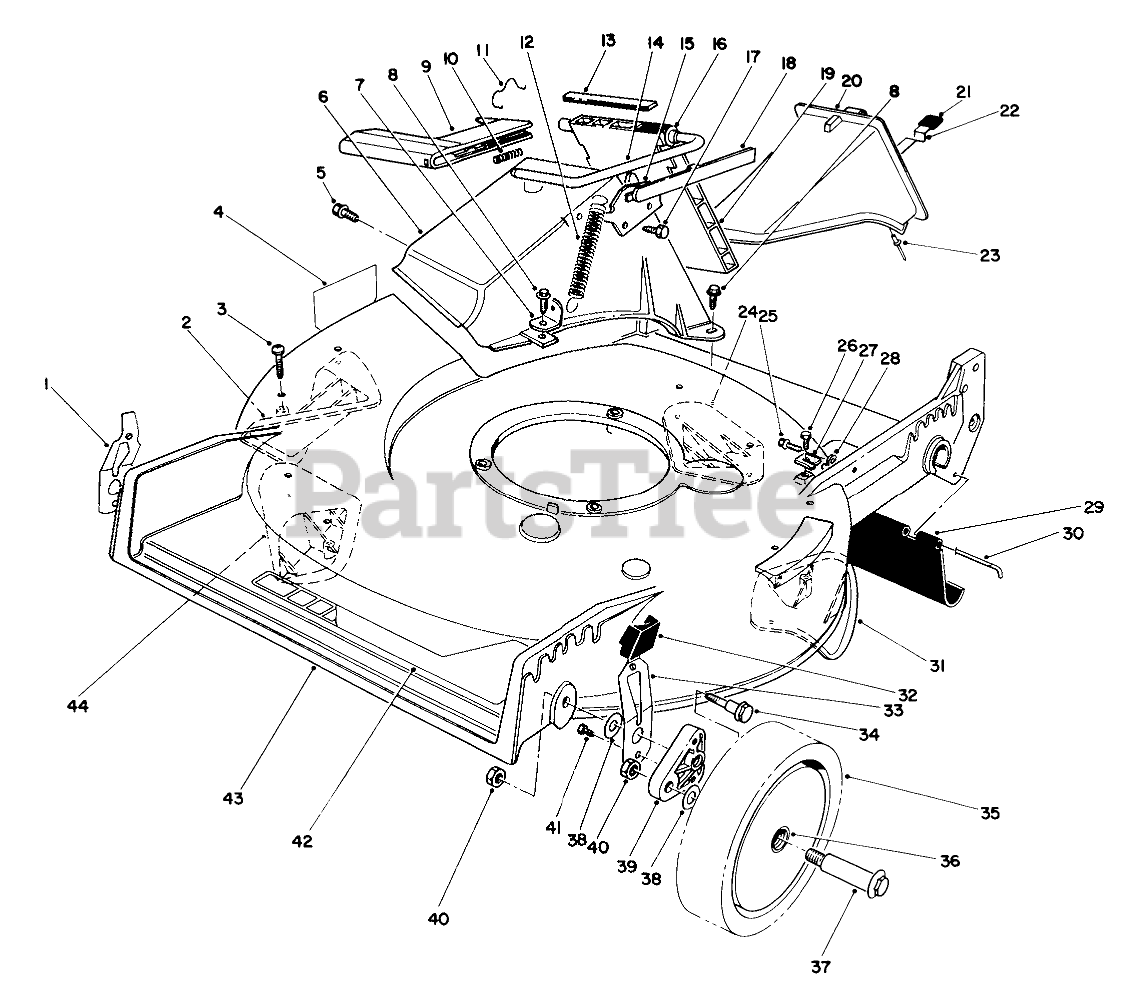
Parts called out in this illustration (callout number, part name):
1	RH SPRING ARM ASSEMBLY
2	KICKER
3	#8 X .625" PHILPS PAN H
4	DECAL-DANGER
5	SCREW AND WASHER ASM
6	Tunnel-Discharge
7	Bracket-Spring
8	SCREW-HWH
9	Handle-Door
10	Spring
11	DOOR RET SPRING
12	SPRING-DOOR
13	Cover-Door
14	Rod-Door
15	DOOR LATCH PLATE
16	BUSHING-NYLON
17	SCREW-PLASTITE
18	Cover-Handle
19	Door-Discharge
20	Plug
21	GRIP-LATCH
22	LATCH-PLUG, DISCHARGE
23	RIVET-HEAD, FLAT
24	PLATE-KICKER
25	SCREW
26	SCREW-HWHTF
27	CLAMP-CABLE
28	CLAMP-CABLE
29	SHIELD-TRAILING
30	ROD-SHIELD
31	KICKER
32	KNOB-ARM
33	LH SPRING ARM ASSEMBLY
34	SCREW-SHOULDER
35	Wheel & Tire Assembly (Incl. Ref. #36)
36	BUSHING
37	WHEEL BOLT
38	WASHER
39	ARM-PIVOT, FRONT
40	Nut
41	SCREW-HWH
42	DECAL - DECK
43	Housing Assembly
44	KICKER
